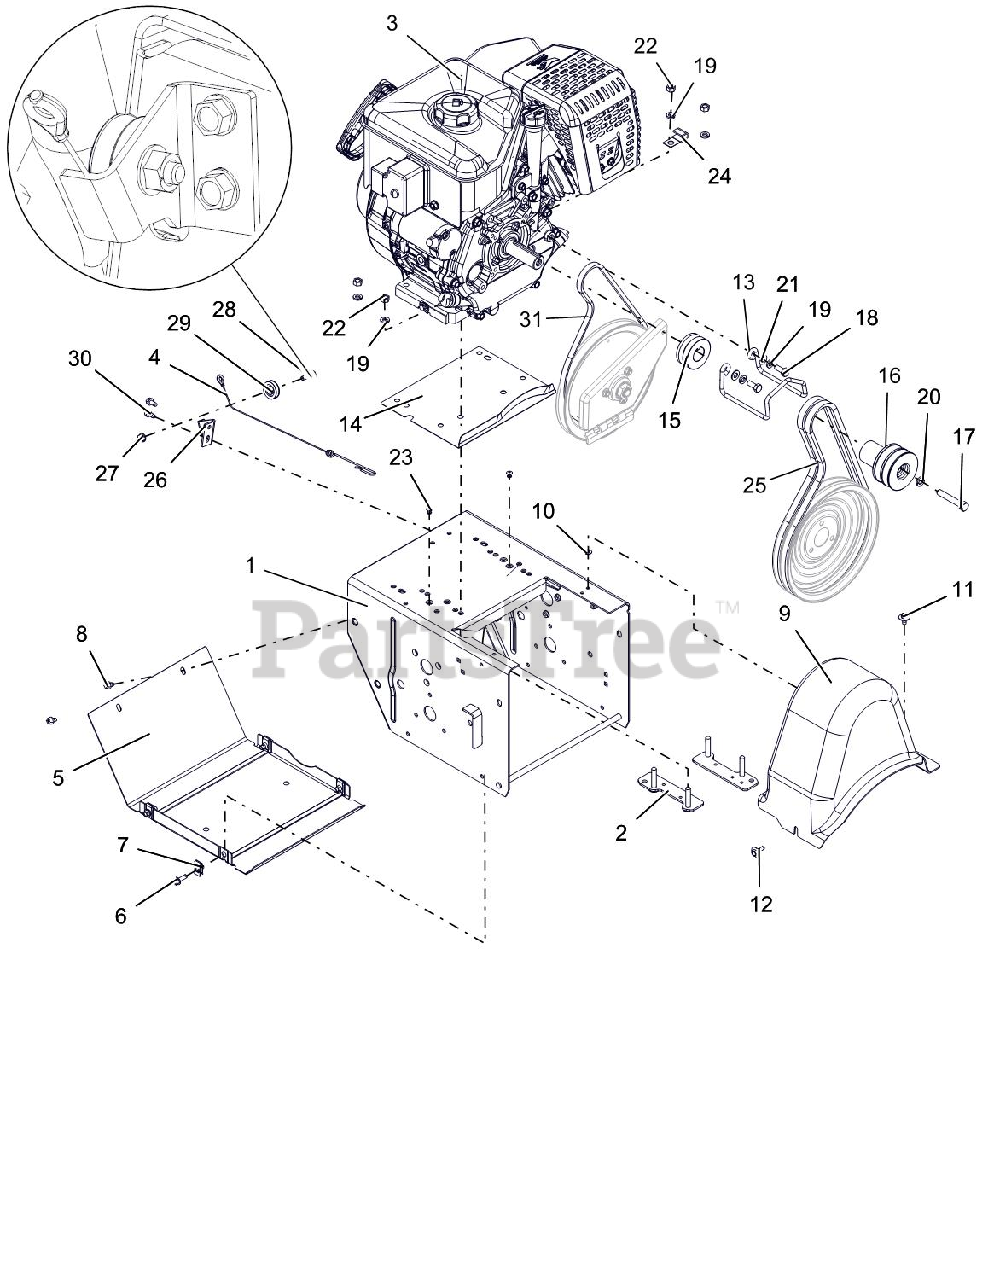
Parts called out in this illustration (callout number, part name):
1	FRAME, MAIN-DELUXE(WELDMENT)
2	STRAP, ENGINE-MEDIUM BLOCK
3	ENGINE,EFI306 GEN3 120V/60W
4	CABLE, LOWER TRACTION,SS & PRO
5	COVER, BOTTOM
6	BLT-HEX .25-20X.75 HWH YZ GR5
7	NUT-RTNR .25-20X.56
8	SCR-TAP .25-20X.50 HWH TR YWZ
9	COVER, BELT-LARGE
10	NUT-PUSH .25X.50 O.D.
11	SCR-TAP .25-20X.50 LGHWH TR YZ
12	SCR-TAP .25-20X.5 CAPTIVE
13	FINGER, BELT
14	BAFFLE, WATER - LARGE BLOCK
15	SHEAVE, DRIVE
16	SHEAVE, ATTACHMENT 2-GRV
17	BLT-HEX .38-24X2.25 YWZC GR5
18	BLT-HEX .31-24X.75 YWZC GR5
19	WSHR-LK .312X.097 HVY YWZC
20	@WSHR-LK .38X.094 REG YWZC
21	@WSHR-FL-STL.344X.688X.065YWZC
22	@NUT-HEX .31-18 YWZC
23	RVT-POP .187 YZ
24	J-CLAMP
25	V-BELT, HA-RAW EDGE (SET)
26	BRACKET, CABLE PULLEY
27	@NUT-LK-TOP-FLG .25-20 YWZC
28	BOLT, SHLDR-.375X.375X.25-20
29	PULLEY, CABLE
30	SCR-TAP .25-20X.50 HWH TR YWZ
31	V-BELT, 3L-WRAPPED
